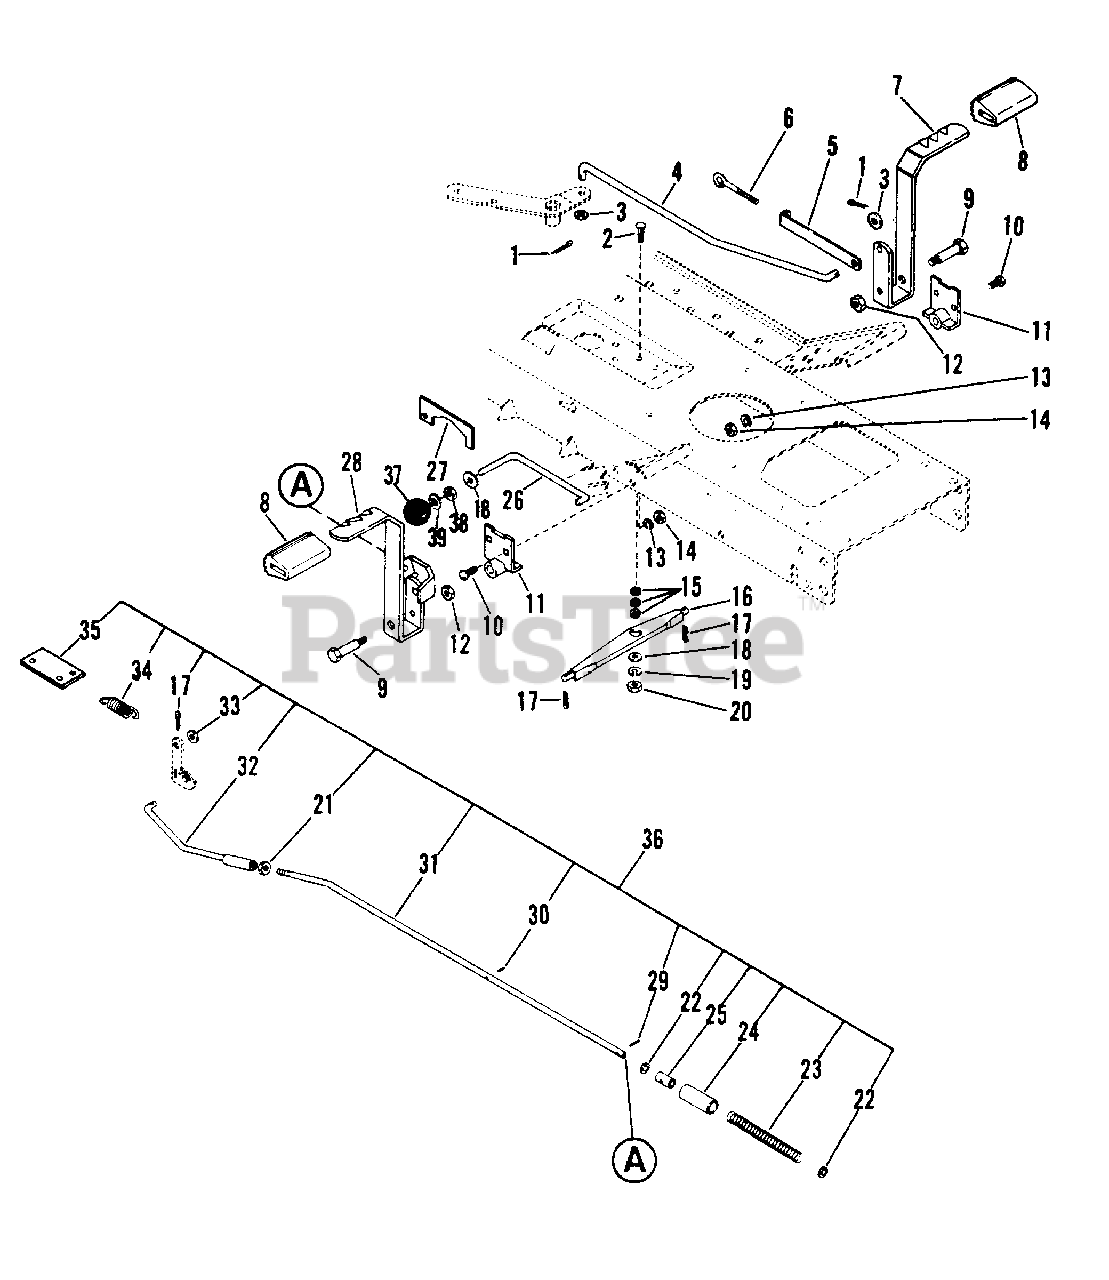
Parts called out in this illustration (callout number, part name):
1	PIN, COTTER .125X1.00
2	BOLT, 3/8-16X1.25 RD HD SQ NK
3	WASHER, FLAT .438X1.000X.083
4	ROD, CLUTCH
5	LINK
6	EYEBOLT
7	PEDAL, CLUTCH
8	COVER, PEDAL
9	BOLT, SHOULDER
10	BOLT, CARRIAGE 5/16-18X.75
11	PIVOT, PEDAL
12	NUT, LOCK 3/8-16
13	WASHER, LOCK 5/16 SP
14	NUT, HEX 5/16-18
15	WASHER, .626 I.D. X 3.85 O.D.
16	ARM, PIVOT
17	HAIRPIN, INTERNAL 3/32
18	WASHER, FLAT .406X.812X.065
19	WASHER, LOCK 3/8 REG.
20	NUT, HEX 3/8-16
21	NUT, HEX 3/8-24
22	WASHER, FLAT .406X.812X.065
23	SPRING
24	SLEEVE
25	SLEEVE
26	ROD, PARKING BRAKE
27	CAM
28	PEDAL, BRAKE
29	PIN, SPRING .125X1.000
30	PIN, SPRING .125X.50
31	ROD, BRAKE
32	ROD, BRAKE
33	WASHER, FLAT .312X.734X.065
34	SPRING, EXTENSION
35	PLATE, ANCHOR
36	ASSEMBLY, BRAKE LINKAGE
37	KNOB, ADJUSTMENT CONTROL
38	NUT, JAM 3/8-16 HEX
39	WASHER, LOCK 3/8 EXT. TOOTH TYA
